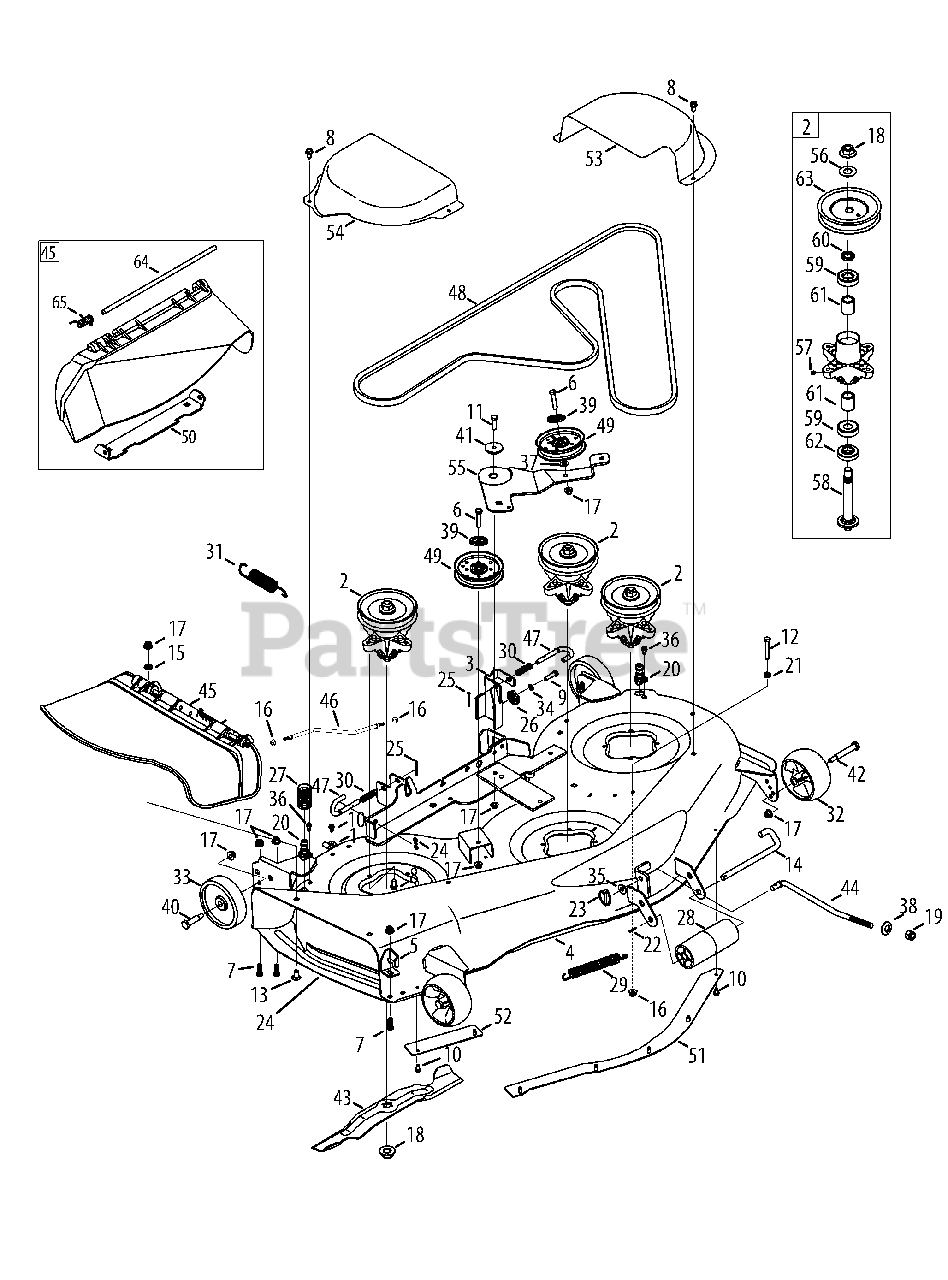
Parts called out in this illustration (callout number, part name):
1	Hook Retainer Bracket
2	Pulley Spindle Assembly, 5.39
3	Deck Hanger Bracket Assembly
4	Deck Assembly
6	Hex Screw, 3/8-16:1.75
7	Hex Screw, 3/8-16:1.00
8	Taptite Screw, 5/16-18:.750
9	Hex Screw, 5/16-18:1.25
10	Taptite Screw, 1/4-20:0.500
11	Hex Screw, 3/8-16:1.25
12	Hex Screw, 5/16-18:2.0
13	Carriage Bolt, 3/8-16:0.75
14	Roller Pin, 1/2 DIA x 7.31 LG
15	Push Nut, 3/8
16	Flangelock Nut, 5/16-18
17	Flangelock Nut, 3/8-16
18	Flange Nut, 5/8-18
19	Flexlock Nut, 1/2-13
20	Deck Wash Nozzle
21	Hex Nut, 5/16-18:GR5
22	Cotter Pin, 3/32:1.0
23	Lynch Pin, .1875
24	Finger Guard
25	Cotter Pin, 1/8 x 1.25
26	Deck Adjustment Gear
27	Water Nozzle Adaptor
28	Front Roller
29	Extension Spring, .94 DIA. x 6.74 LG
30	Compression Spring, .535 OD x 1.751 LG
31	Extension Spring, 1.15 OD x 5.99 LG
32	Front Deck Wheel
33	Rear Deck Wheel
34	Lock Washer, 5/16
35	Flat Washer, .531 x 1.25 x .100
36	Shoulder Screw, 1/4-20 x 0.50
37	Flat Washer, .406 x .875 x .059
38	Bell Washer, .63 x 1.25 x .18
39	Pulley Cap
40	Shoulder Bolt, .496 x 1.525:3/8-16
41	Shoulder Spacer, .8840 x .190
42	Shoulder Bolt, .496 x 2.50:3/8-16
44	Front Deck Lift Rod
45	Chute Assembly
46	Deck Sway Rod
47	Deck Release Handle Rod
48	V Belt
49	Idler Pulley, 4.25"DIA
50	Chute Bracket
51	Center Skirt
52	RH Skirt
53	LH Belt Cover
54	RH Belt Cover
55	Idler Bracket
56	Flat Washer, .760 x 1.50 x .120
57	Lube Fitting
58	Spindle Shaft
59	Ball Bearing, .787ID x 1.85
60	Spacer, .790 ID x 1.25 OD x .175
61	Spacer, .80 x 1.10 x 1.322
62	Spacer, .79 x 1.82 x .55
63	Deck Pulley
64	Hinge Pin
65	Torsion Spring
